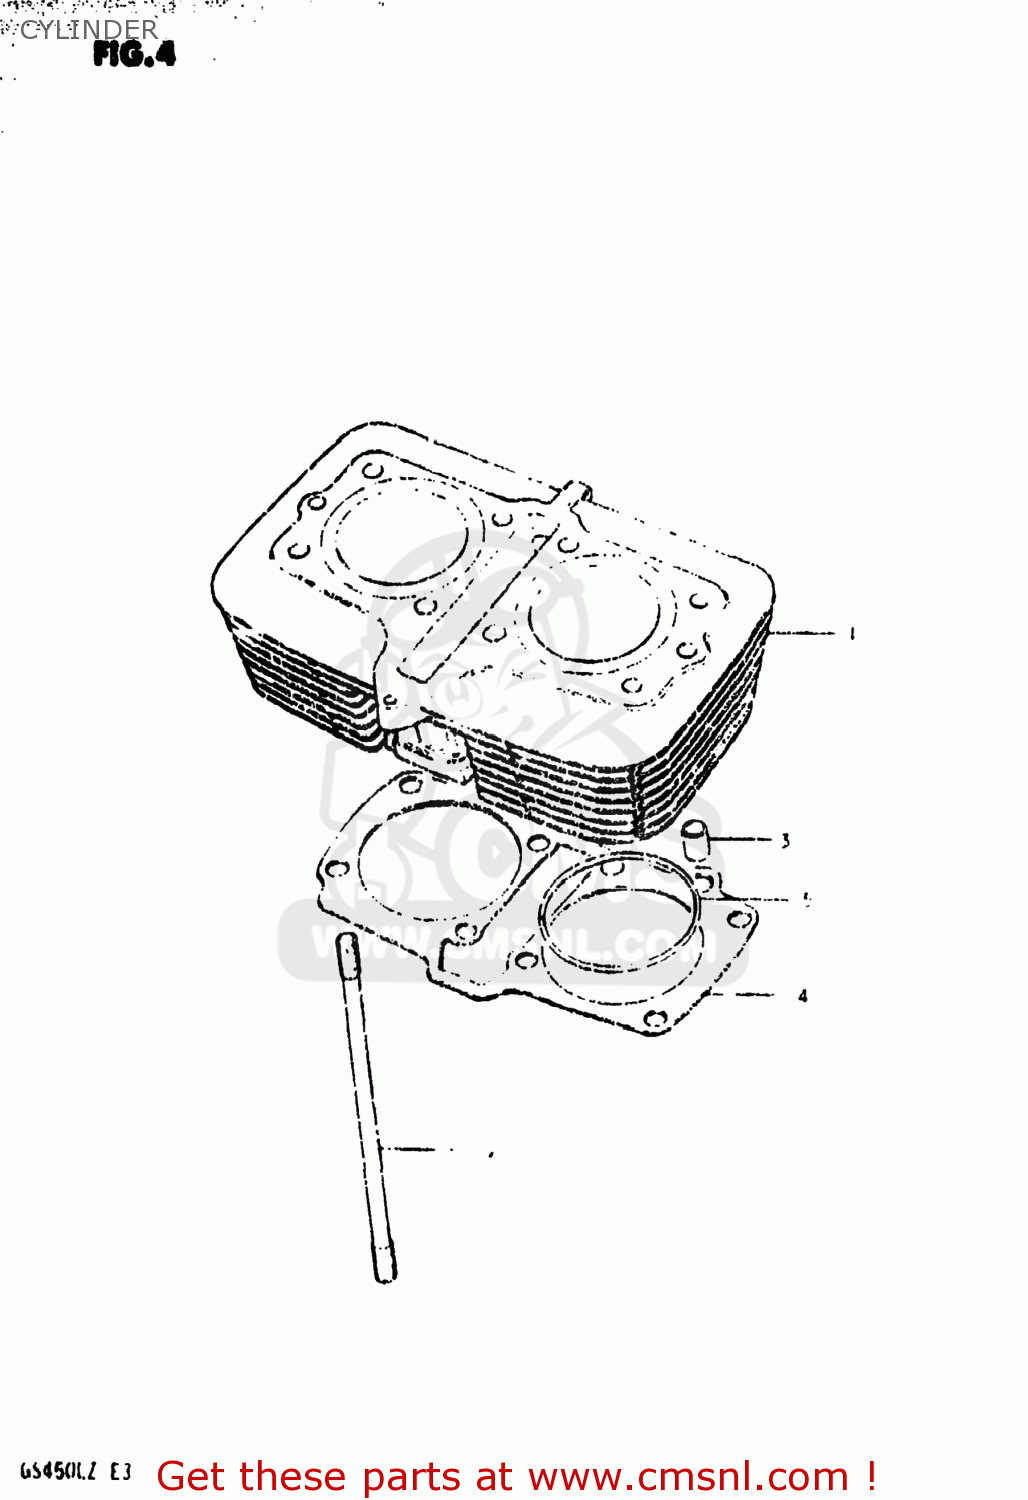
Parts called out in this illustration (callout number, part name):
1	CYLINDER
2	STUD
3	PIN
4	GASKET,CYLINDER (MCA)
5	O RING(D:2,ID:74)
